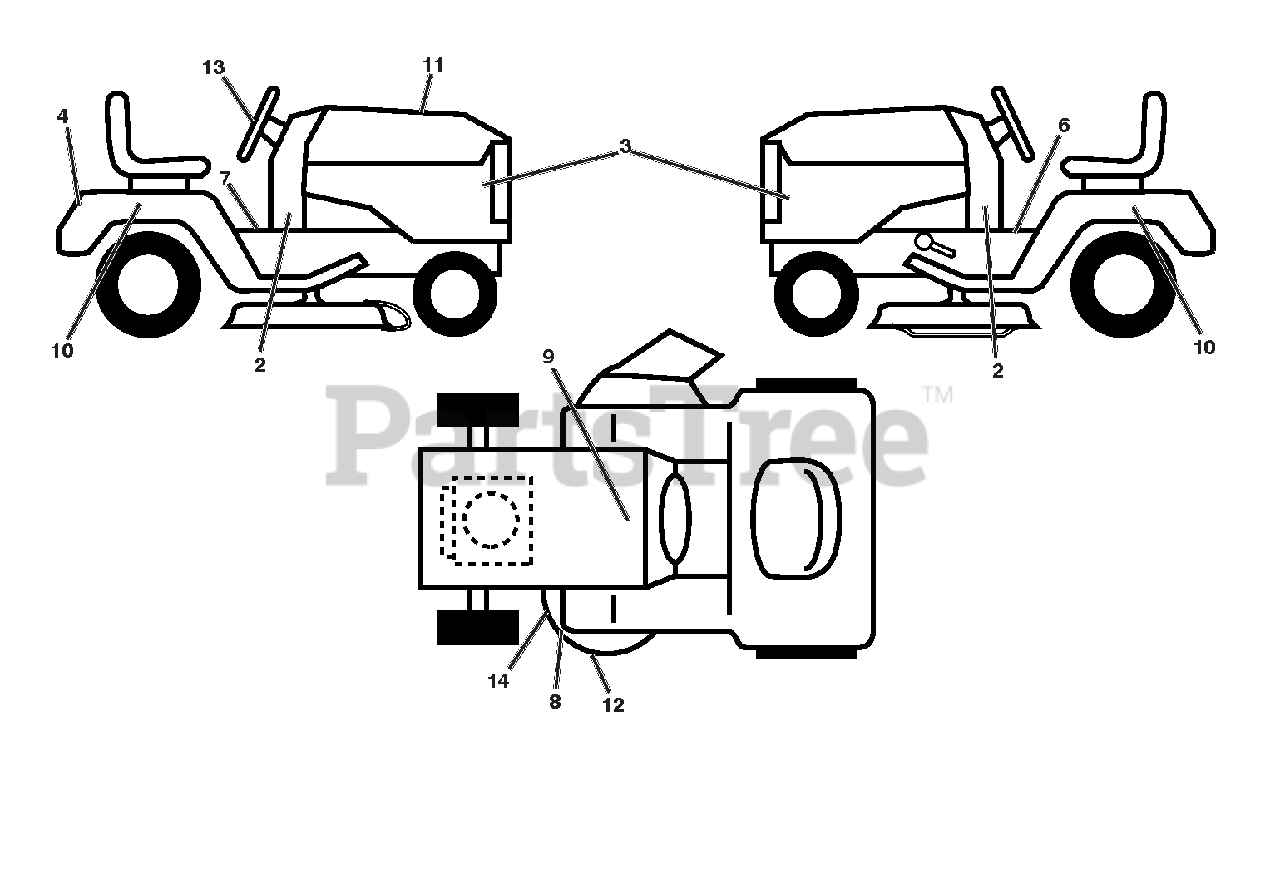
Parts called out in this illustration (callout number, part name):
2	DECAL.LOWER.DASH
3	DECAL.SDPNL.PWRDBY KOHL.ARIENS
4	DECAL.FENDER.REAR.ARIENS
6	DECAL, WARNING START INST.
7	DECAL.FENDER
8	DECAL.WARNING.KEEP.HAND.AWY
9	DECAL.BAT.DAN/POI P/L SYM.WPN
10	DECAL.FENDER.SIDE.HYDRO.ARIENS
11	DECAL.RPL.KH.TWIN.TLW.54.0510
12	DECAL.MOWER.SCH
13	DECAL.WHEEL.STEER.ARIENS
14	DECAL.MOWER.CAUTION
